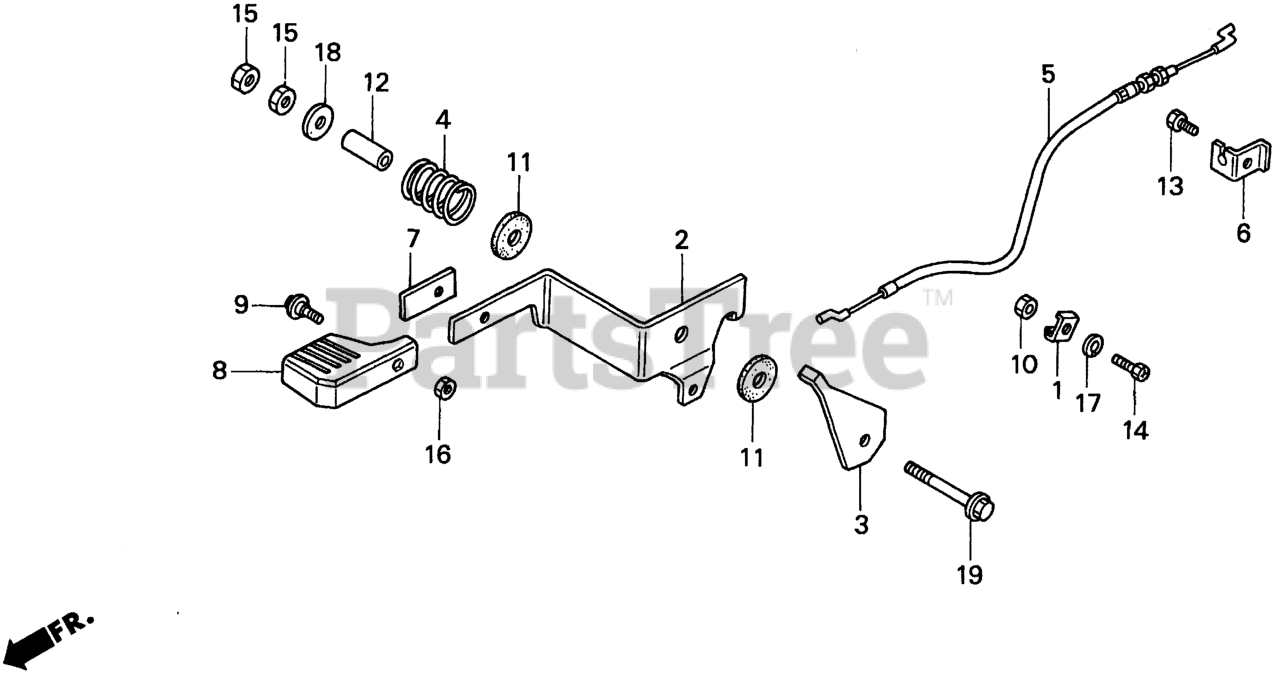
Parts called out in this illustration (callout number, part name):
1	HOLDER, CABLE
2	LEVER, THROTTLE
3	PLATE, FRICTION STOP
4	SPRING, THROTTLE LEVER
5	CABLE, THROTTLE
6	HOLDER, CABLE
7	PLATE, SPACER
8	KNOB B, CHANGE LEVER *YR161* (ORANGE)
9	SCREW, HEADLIGHT SETTING
10	NUT, SELF-LOCK (5MM)
11	WASHER, FRICTION
12	COLLAR, THROTTLE
13	BOLT, RECESSED (5X12)
14	BOLT, RECESSED (5X16)
15	NUT, HEX. (6MM)
16	NUT, HEX. (5MM)
17	WASHER, PLAIN (5MM)
18	WASHER, PLAIN (6MM)
19	BOLT, FLANGE (6X50)
